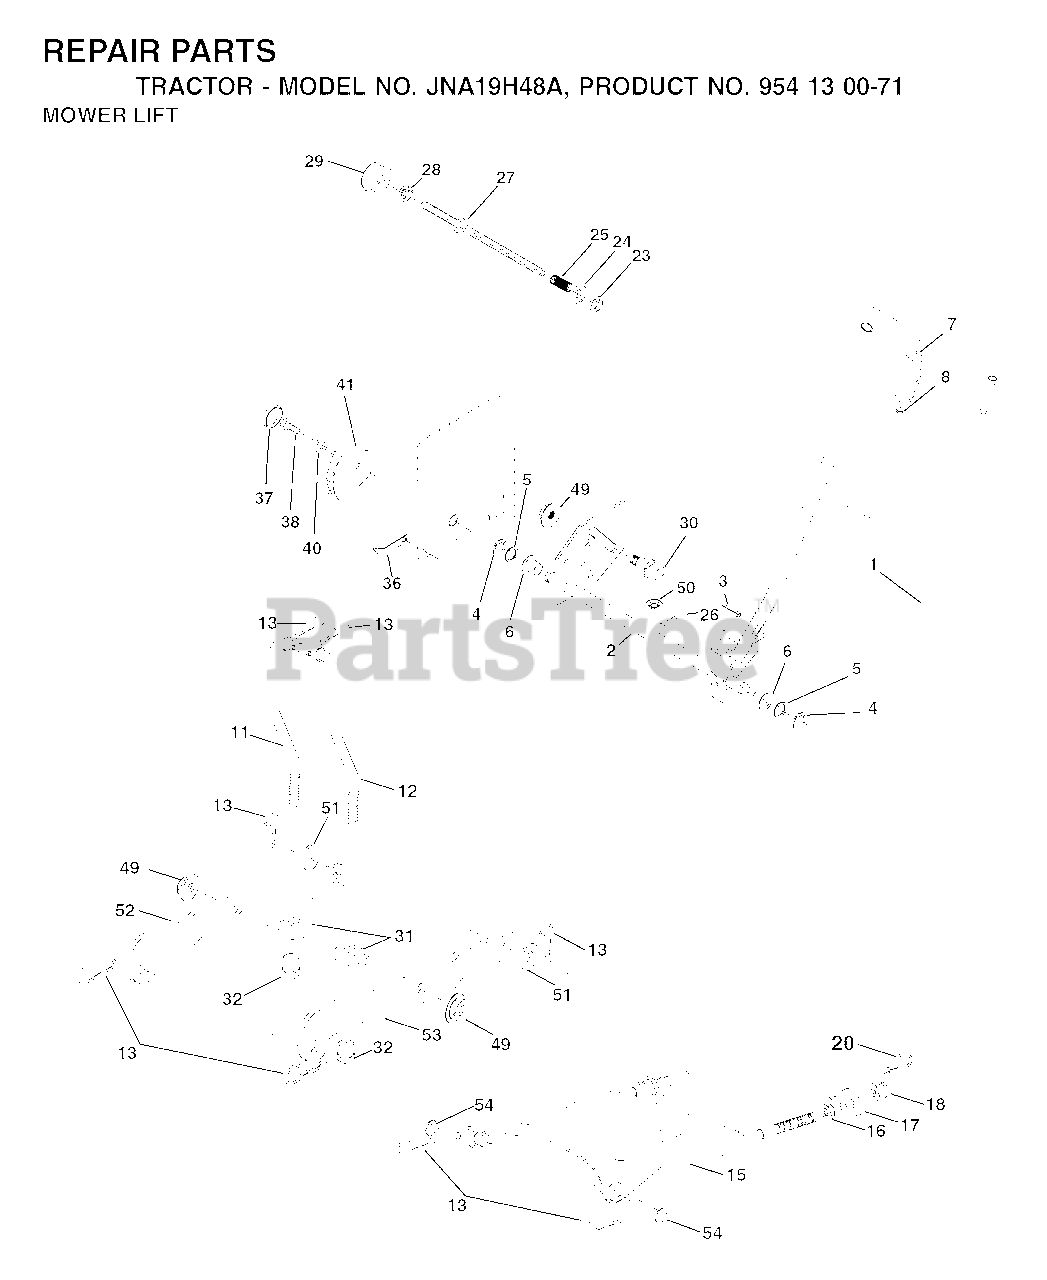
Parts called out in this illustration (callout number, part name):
1	WIRE ASM INNER W/ PLUNGER LT
2	SHAFT ASM R HANDLE
3	PIN GROOVE
4	RETAINING RING LT
6	BEARING.NYLON
7	GRIP HANDLE
8	PLUNGER BUT KIT
11	LIFT LINK LH
12	LIFT LINK RH
13	RETAINER-SPRNG RB
15	PLATE ASM SUSP FRONT
16	NUT
18	NUT
20	SPRING RETAINER
25	SPRING**
26	RETAINER CLIP
27	ROD ADJ LIFT
28	NUT
29	KNOB INF 3/8-16
32	NUT, LIFT LINK 7/16-20
36	POINTER, HEIGHT INDICATOR
37	PLUG,HOLE
38	SCREW 5/16-18X1
41	IND. HEIGHT STLT
49	NUT
50	NUT PUSH M
52	ARM SUSP. REAR LH
53	ARM SUSP REAR RH
54	PIN, FLANGE
